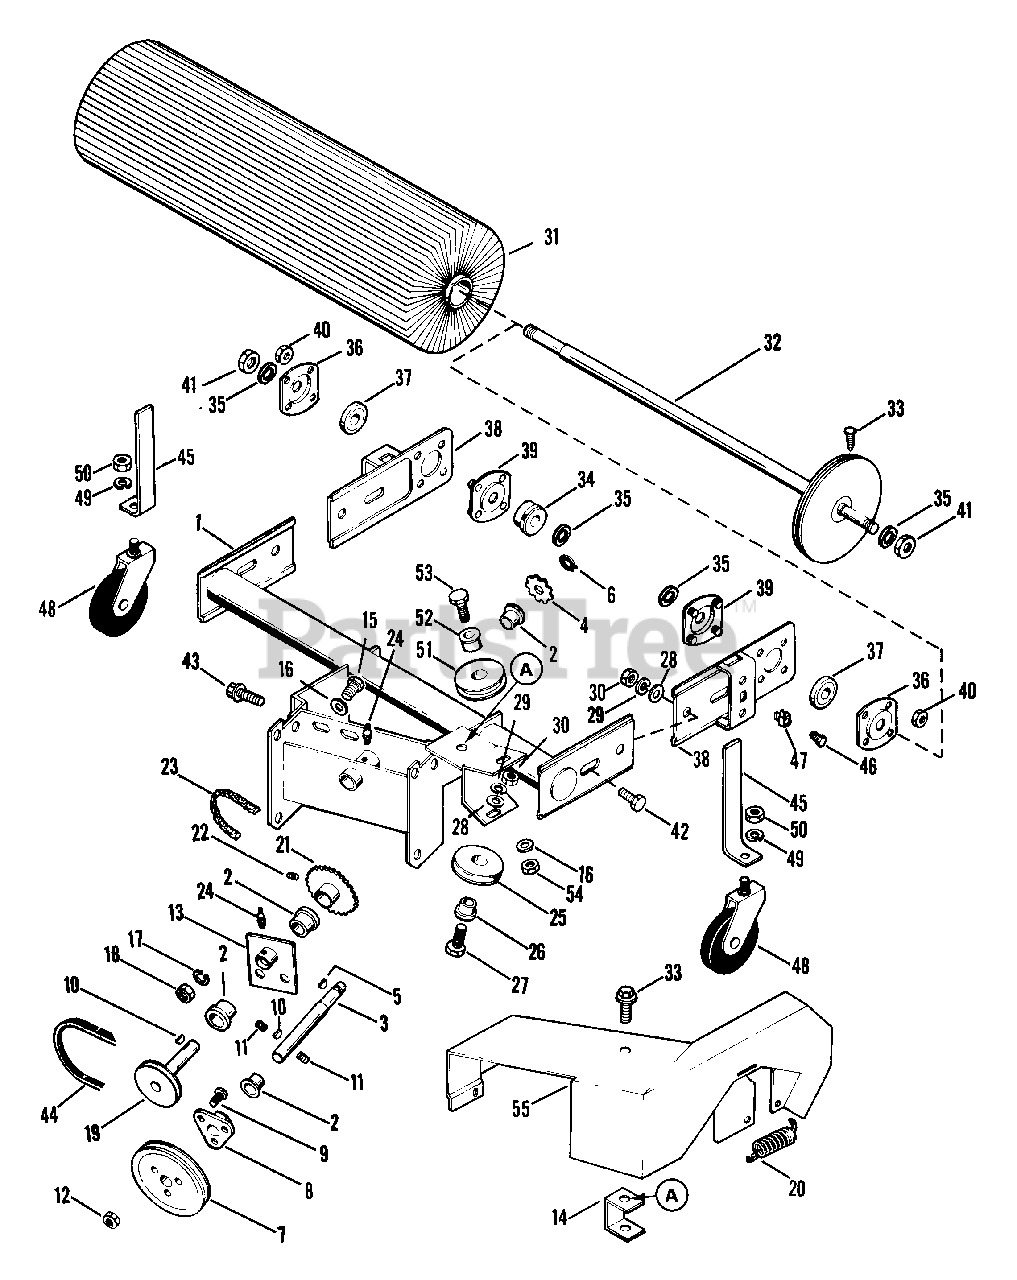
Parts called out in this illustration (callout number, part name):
1	BRUSH FRAME
2	BSHG-FLG .750X1.000X.625X1.250
4	9 TOOTH SPROCKET
5	KEY-WDRF .125X.625X.250 SAE5
6	RG-RTNG-EXT .500X.035
7	PLY-V 7.0 X 1.25 3BLT
8	HUB
9	BLT-SERRDHD SL .31-18X.75 YZ
10	KEY-WDRF .188X.75X.313 SAE 9
11	SCR-SET .32-18X.38 SKHCUPNL OH
12	NUT-FLG. .312-18 PL
13	SPINDLE HOUSING
14	BRACKET
15	BLT-HEX .38-16X1.00 PL
16	WSHR-FL-STL .438X1.0X.083 PL
17	WSHR-LK .375X.115 HVY PL
18	NUT-HEX .375-16
19	SPINDLE
20	SG-TENS .048X.44X1.75 WLD 9
21	SPROCKET
22	SCR-SET .32-18X.38 SKHCUPNL OH
23	CHAIN
24	SPIN DRIVE ZERK FITTING
25	IDLER-V 3.50 X .50 CAPITOL
26	SPCR, BRG .315X.50X.688X.281
27	BLT-HEX .31-18X1.50 PL GR2
28	WSHR-FL-STL .38X.875X.083 PL
29	WSHR-LK .312X.097 PL HVY
30	NUT-HEX .312-18
32	BRUSH SHAFT
33	BLT-SERHFWH .31-18X.50 PL
35	WSHR-FL-STL .531X1.062X.095 PL
36	BEARING FLANGE
37	BRG-BALL .500X1.38X.437
38	ARM
39	BEARING FLANGE
40	NUT-LK DUAL FACE 10-24 PL
41	NUT-LK-CTR .50-20 PL
42	BLT-HEX .31-18X.75 PL GR2
43	BLT-SERHFWH .31-18X.75 PL
44	V-BELT, 4L-WRAPPED C-L2089
45	ADJUSTMENT LEG
46	SCR-SET .38-16X.75 SQHCUP HT
47	NUT-RETNR .38-16 TINRMAN
49	WSHR-LK .500X.151 HVY PL
50	NUT .50-13 PL
51	IDLER-FLAT 3.00 X .38 CLK.&CAP
52	SPACER .379X.625X.500
53	BLT-HEX .38-16X1.50 PL GR2
54	NUT-LK-CTR .375-16 GR A PL
55	BELT COVER
